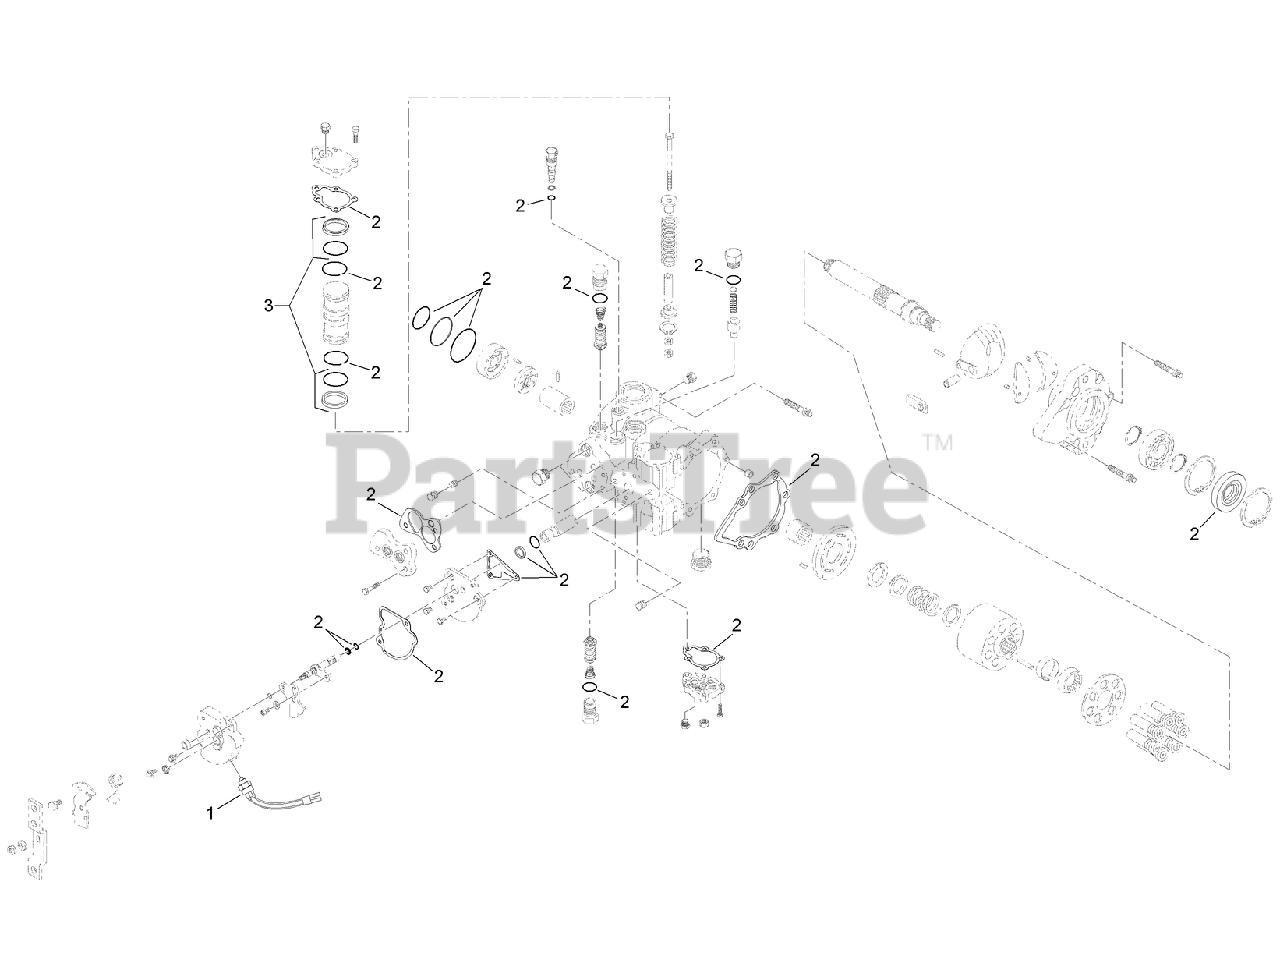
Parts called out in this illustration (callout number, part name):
1	SWITCH-NEUTRAL
2	Overhaul Service Seal Kit - Purchase from Sauer-Danfoss Dealer
3	PISTON RING AND O-RING KIT
